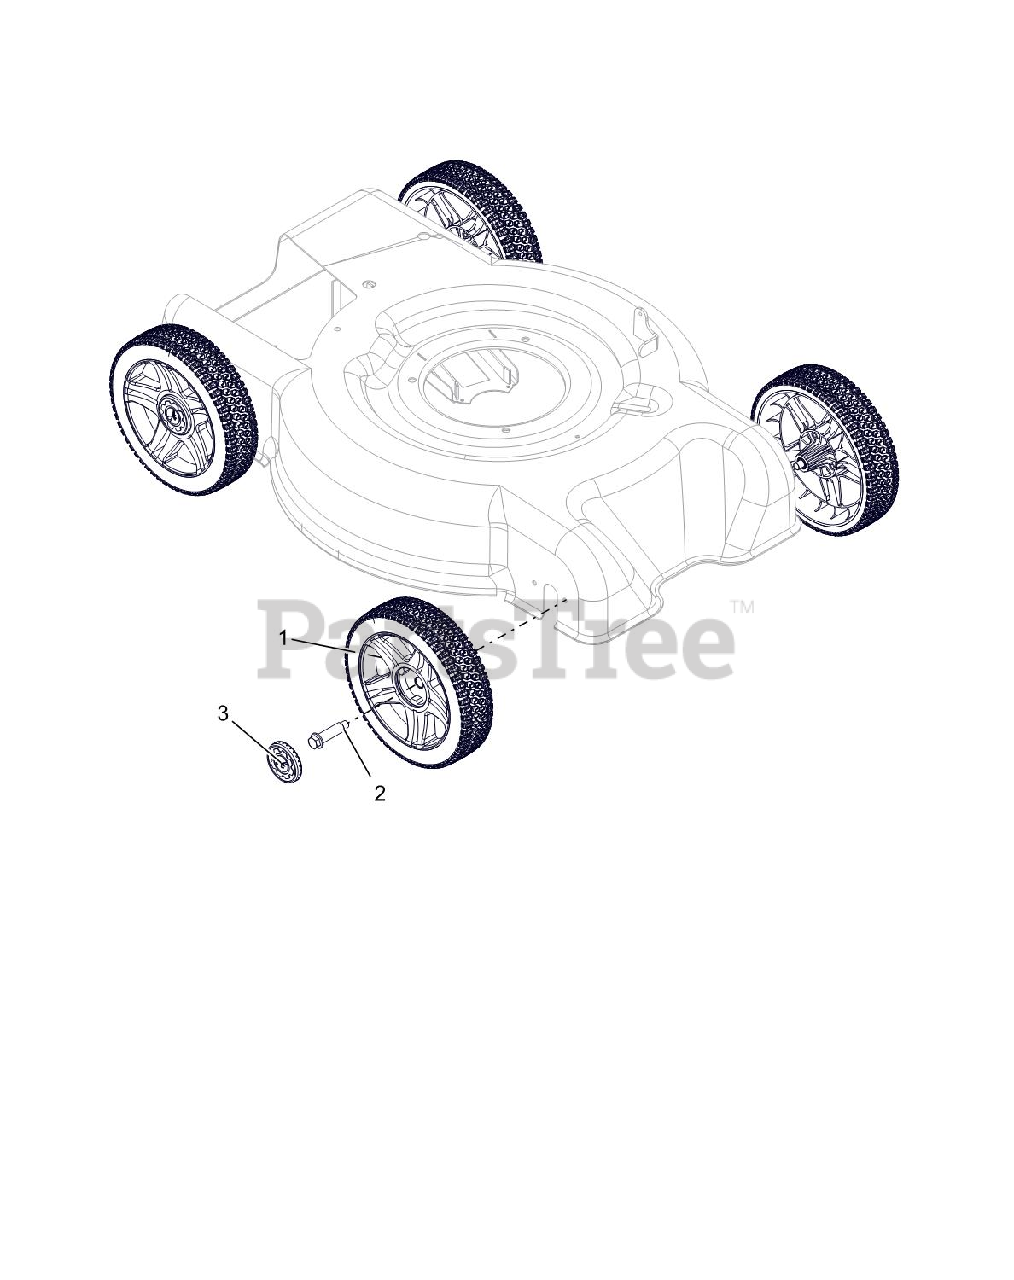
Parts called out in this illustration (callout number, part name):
1	ASSEMBLY, RAZOR WHEEL/BSHG
2	BOLT, WHEEL SHOULDER
3	CAP, LM WHEEL HUB
